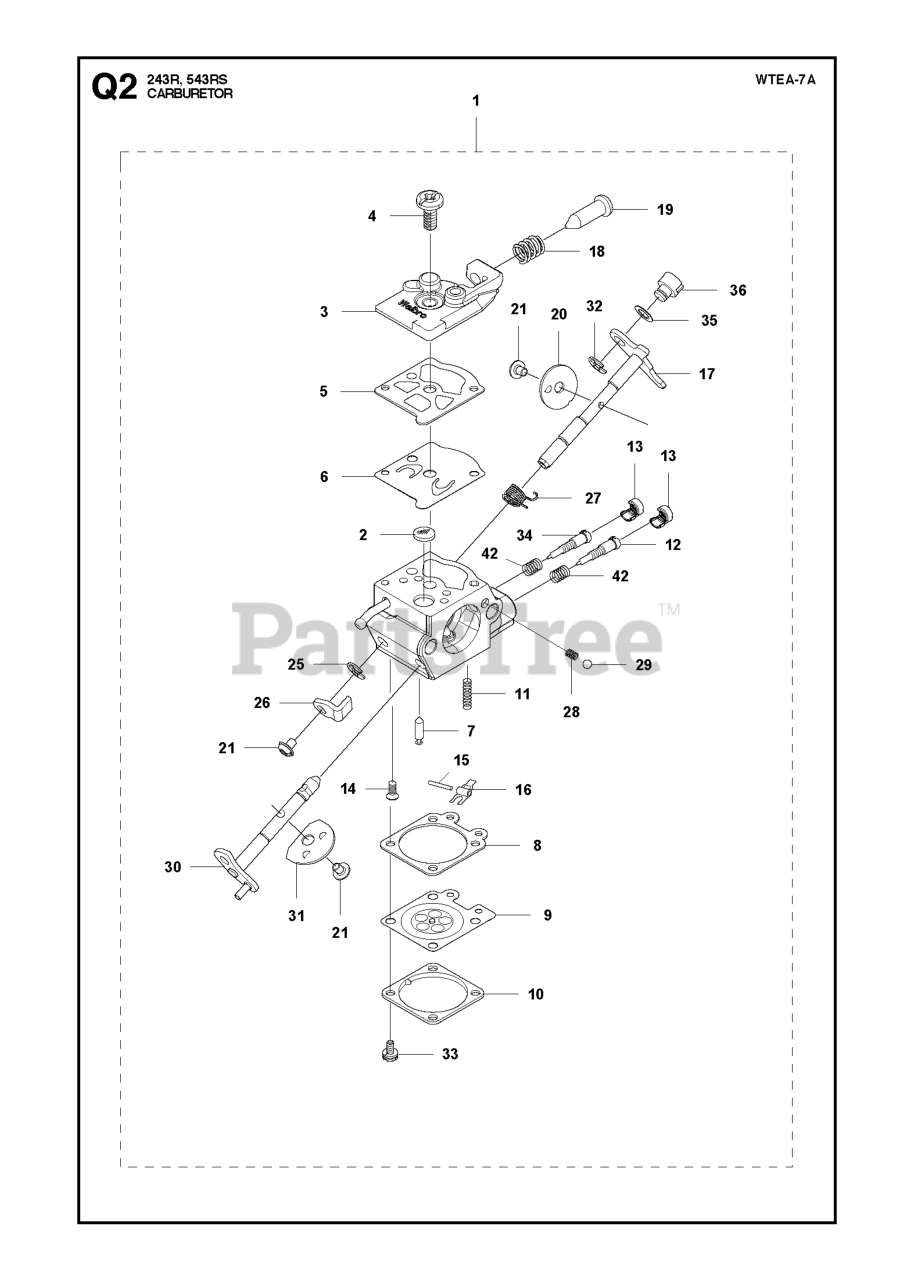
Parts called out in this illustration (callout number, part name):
1	CARBURETOR ASSY WTEA-4A
2	SCREEN
3	COVER
4	SCREW
5	GASKET
6	DIAPHRAGM
7	VALVE INLET
8	GASKET
9	DIAPHRAGM
10	COVER
11	SPRING
12	NEEDLE H
13	CAP LIMITER
14	SCREW
15	PIN
16	LEVER
17	SHAFT ASSY THROTTLE
18	SPRING
19	SCREW, IDLE
20	VALVE, THROTTLE
21	SCREW
25	E-RING
26	LEVER THROTTLE
27	SPRING
28	CHOKE SPRING
29	BALL
30	SHAFT ASSY CHOKE
31	VALVE CHOKE
32	RING
33	SCREW ASSY
34	NEEDLE L
35	WASHER
36	SWIVEL
42	SPRING
